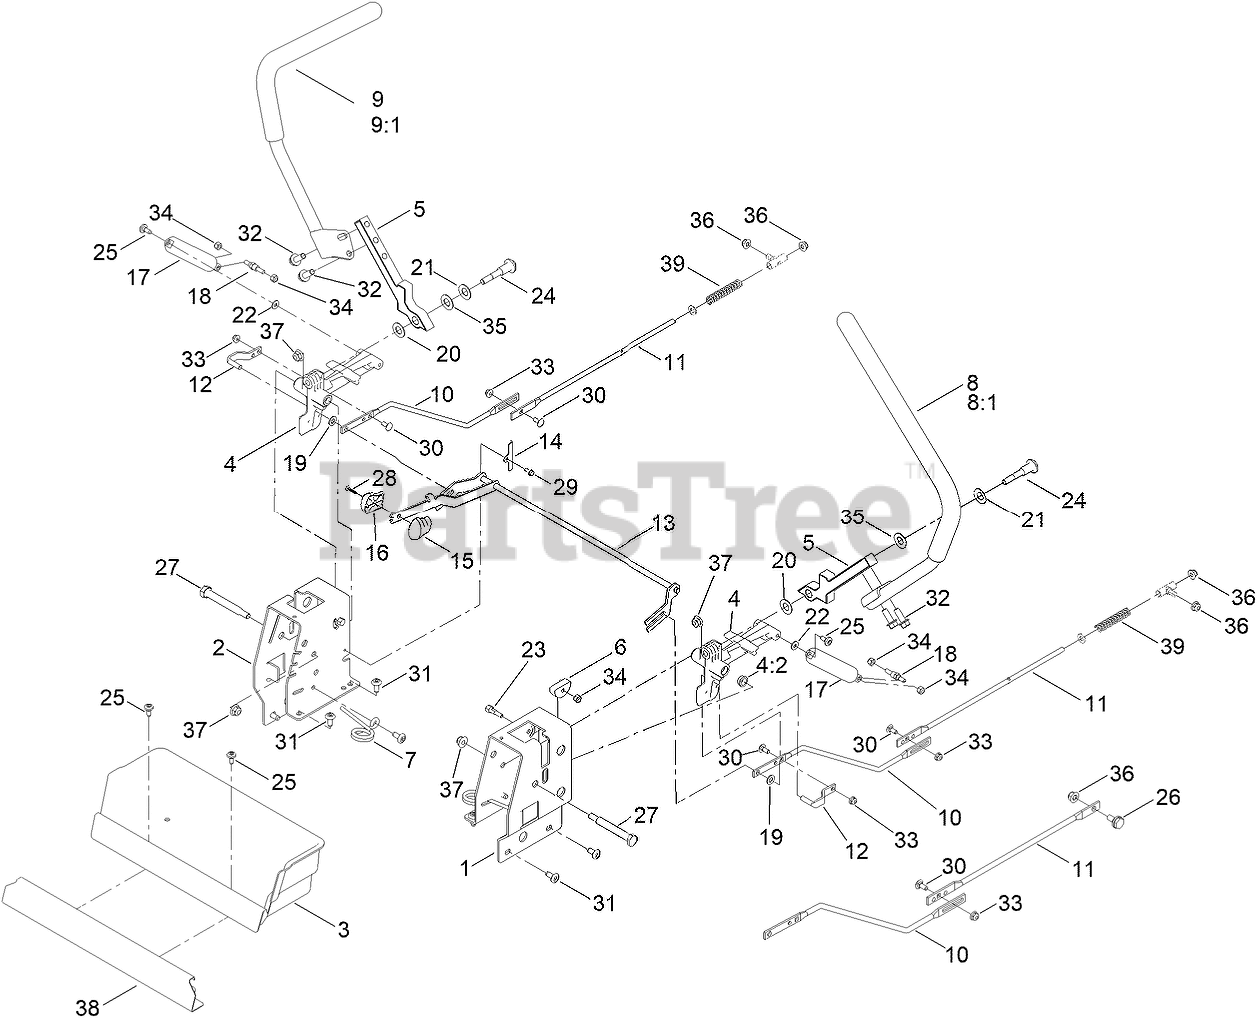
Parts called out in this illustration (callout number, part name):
1	PLATE-CONTROL BOX, LH
2	PLATE-CONTROL BOX, RH
3	BOX-STORAGE
4	ACTUATOR ARM ASM
4:2	BUSHING-FLANGE
5	ARM-CONTROL
6	ECCENTRIC
7	SPRING-TORSION
8	HANDLE-CONTROL, LH
9	HANDLE-CONTROL, RH
10	ROD-HYDRO, FRONT
11	ROD-HYDRO, REAR
12	PIN-ROD, HYDRO
13	SPEED CONTROL ASM
14	PLATE-RETAINER
15	KNOB-RH
16	KNOB-LH
17	DAMPER-NON CAVITATING
18	STUD-DAMPER
19	SPACER-NYLON
20	WASHER-NYLON
21	WASHER-BELLEVILLE
22	WASHER
23	BOLT-PIVOT, ECCENTRIC
24	BOLT-PIVOT
25	SCREW-SHOULDER
26	BOLT-SHOULDER,HFH
27	BOLT-PIVOT
28	SCREW-PPH
29	SCREW-TAPTITE
30	SCREW-CARR
32	SCREW-HHF
33	NUT-HF
34	NUT-LOCK, NI
35	WASHER
36	NUT-HF
37	NUT-HF, NI
38	PLATE-KICK
39	BOLT-SHOULDER,HFH
